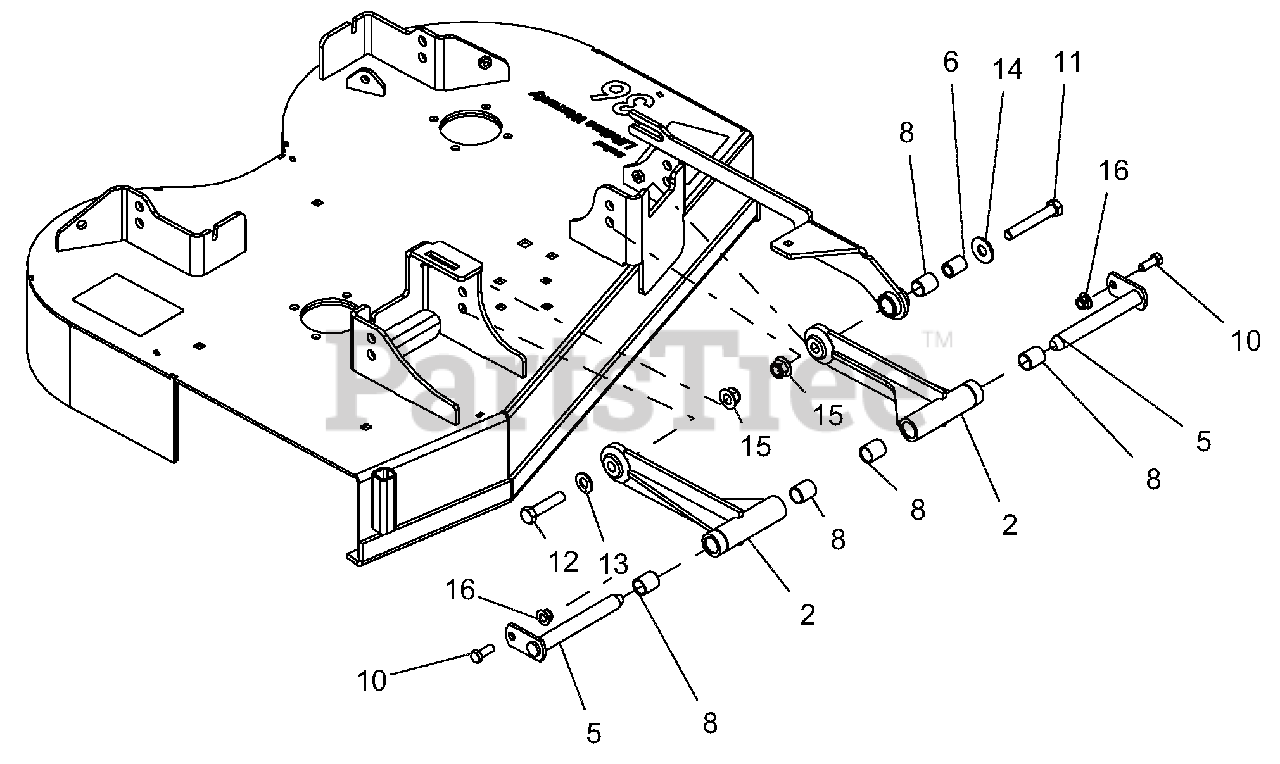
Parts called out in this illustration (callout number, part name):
2	WLDMT, DRAG LINK
5	WLDMT, MOWER MTG. PIN
6	BSHG, .515ID X .750OD X 1.040
8	BRG, .75 X .875 X 1.00
10	BLT-HEX .38-16X1.00 GR5 YWZC
11	BLT-HEX .50-13X3.25 GR5 YWZC
12	BLT-HEX .50-13X2.25 GR5 YWZC
13	WSHR-FL-STL.531X1.06X.095YWZC
14	WSHR-FL-STL.563X1.38X.109YWZC
15	NUT-LK-NYL-FLG .50-13 YWZC
16	NUT-LK-NYL-FLG .38-16 YWZC
